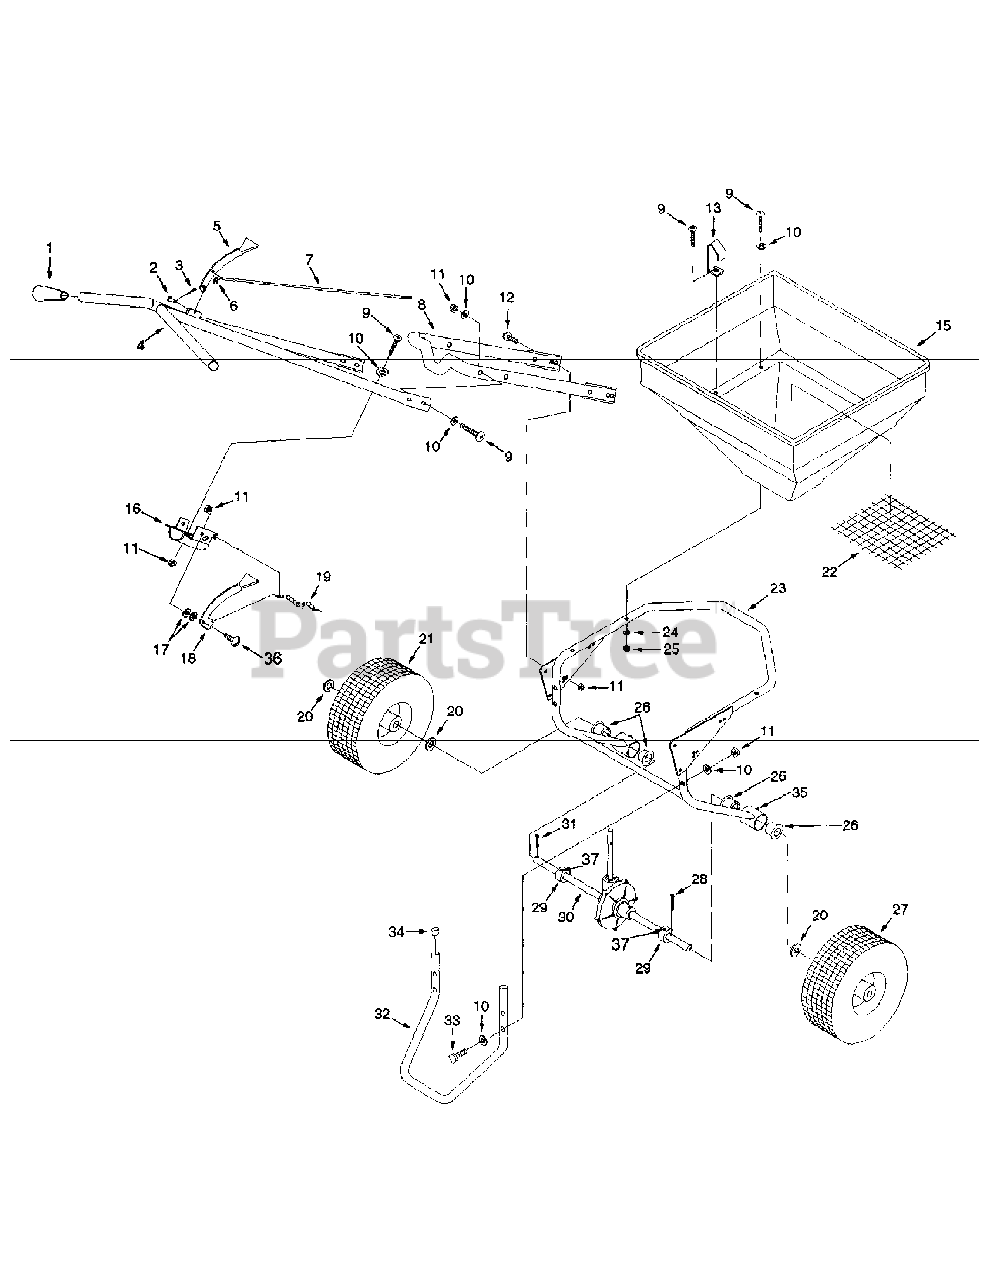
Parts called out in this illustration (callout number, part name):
1	Handle Grip
2	Clevis Pin, 1/4 x 1/2, SS
3	Cotter Pin, 3/32 x 1/2, SS
4	Upper Handle, SS
5	Operating Lever, SS and Rubber Knob
6	C-Clip
7	Lever Rod, SS
8	Lower Handle, SS
9	Machine Screw, 1/4-20 x 1-1/2, SS
10	Flat Washer, 1/4, SS
11	Hex Nut, 1/4-20 Nylock, SS
12	Machine Screw, 1/4-20 x 5/8, SS
13	Screen Clip, SS
15	Hopper
16	Bracket, Dual Remote, SS
17	Flat Washer, 1/4, Nylon
18	Remote Cable Lever, SS and Rubber Knob
19	Cable, Remote Control
20	Spacer Washer, SS
21	Idler Wheel, Composite
22	Hopper Screen
23	Frame
24	Lock Washer, 1/4, SS
25	Hex Nut, 1/4-20, SS
26	Axle Bushing, Composite
27	Drive Wheel, Composite
28	Cotter Pin, 3/16 x 1-3/4, SS
29	Shaft Collar, SS
30	Spreader Axle, SS
32	Leg, SS
33	Cap Screw, 1/4-20 x 2-1/4, SS
34	Plastic Plug
35	Grease Fitting,1/4-28 Straight
36	Pan Hd. Mach. Scr. 1/4-20 x 7/8
37	Set Screw
